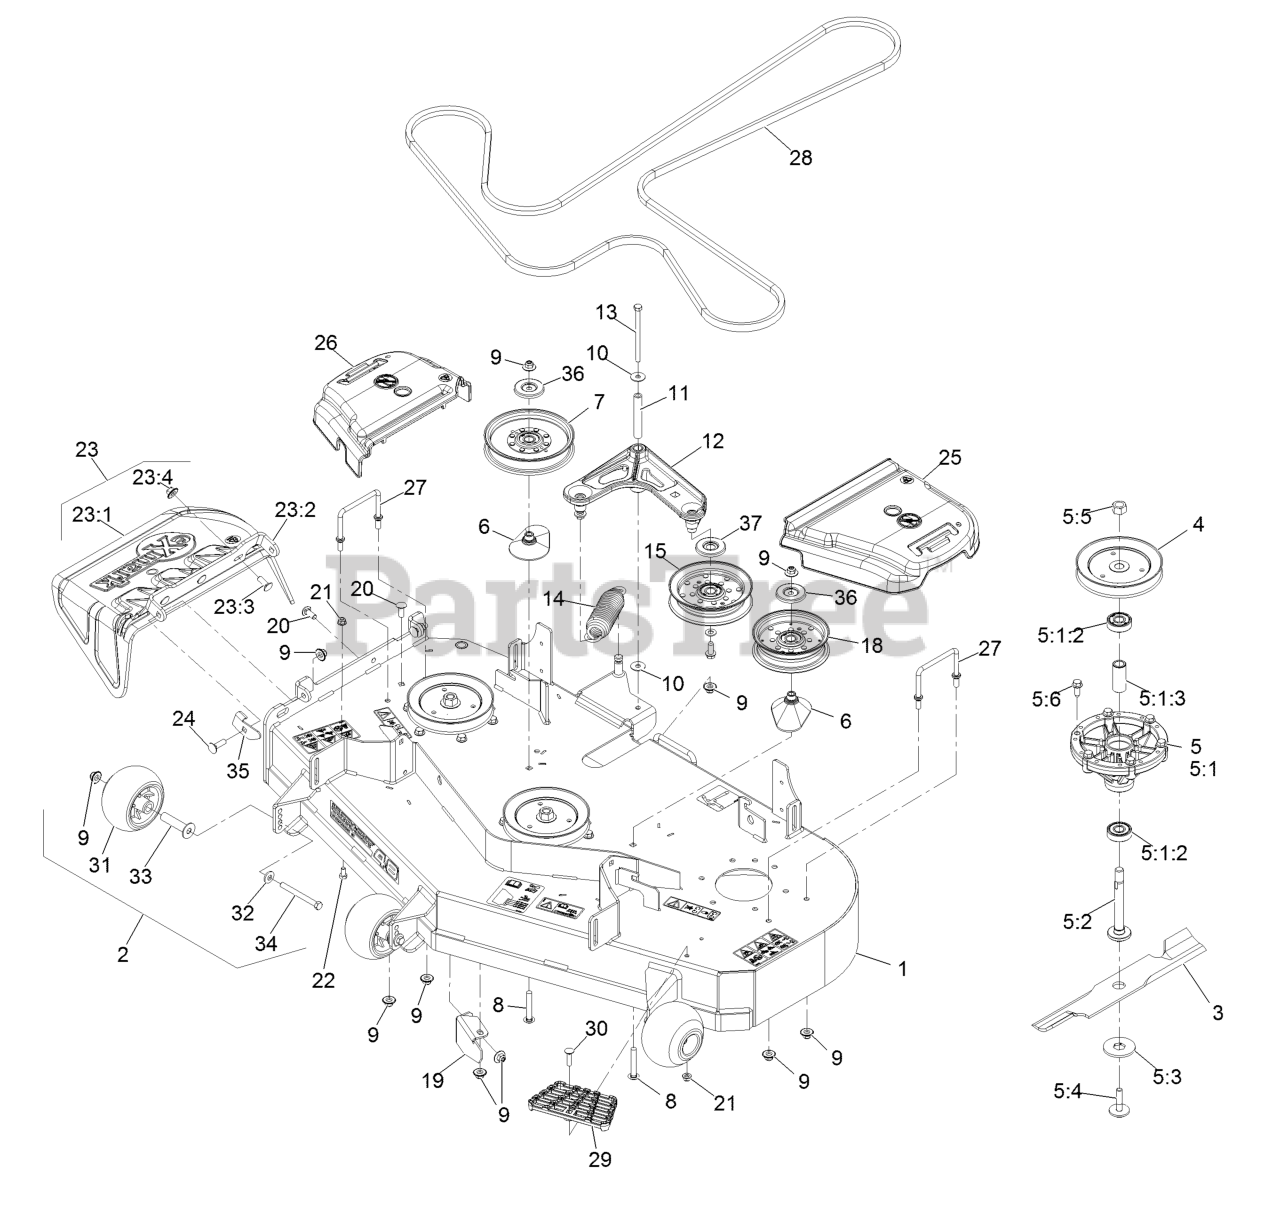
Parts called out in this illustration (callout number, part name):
1	ASM-Deck W/Decals 483
2	Kit, Anti-Scalp Roller
3	Blade, Mulching
3	Blade, Low Lift
3	Blade, Solid
3	Blade-Notched
3	Blade-Extreme 2, 16.25"
4	Sheave,Blade Drive 5.90
5	ASM, Cutter Housing Complete
5:1	ASM-Cutter Housing
5:1:2	Bearing
5:1:3	Spacer-Bearing
5:2	Spindle-Hex Pilot
5:3	Washer-Hex Blade Drive
5:4	Bolt-Blade, Sem
5:5	Nut-Hex 5/8-18
5:6	Screw-Forming, Thread
6	Spacer-Pulley
7	Idler-Pulley, Flat 6.00X1.00
8	Bolt-Carriage 3/8-16 X 2 1/2
9	Nut-Nyloc 3/8-16 Flg
11	Bushing
12	Idler Arm ASM
13	Screw-HH 3/8-16 X 4 3/4
14	Spring-Extension
15	Idler-Pulley, Flat
18	Idler-Pulley, Flat 5.00X1.31
19	Baffle,Discharge 483
20	Bolt-Carriage 3/8-16 X 1
21	Nut-Nyloc 5/16-18 Flg
22	Screw-HH 5/16-18 X 5/8
23	ASM,Discharge Chute
23:1	Chute, Discharge
23:2	Bracket,Discharge Chute
23:3	Bolt-Carriage 3/8-16 X 1
23:4	Nut-Nyloc 3/8-16 Flg
24	Bolt-Carriage 3/8-16 X 1 1/4
25	Cover-Belt, LH
26	Cover-Belt, RH
27	Wireform-Cover
28	Belt-V
29	Step-Deck
30	Bolt-Carriage 5/16-18 X 1 1/4
31	Roller-Anti-Scalp
32	Washer-Spring Disc 3/8
33	Axle, Roller
34	Screw-HH 3/8-16 X 3 3/4 GR 8
35	Stop-Discharge Chute
36	Shield-Dust
37	Shield-Guard, Dust
